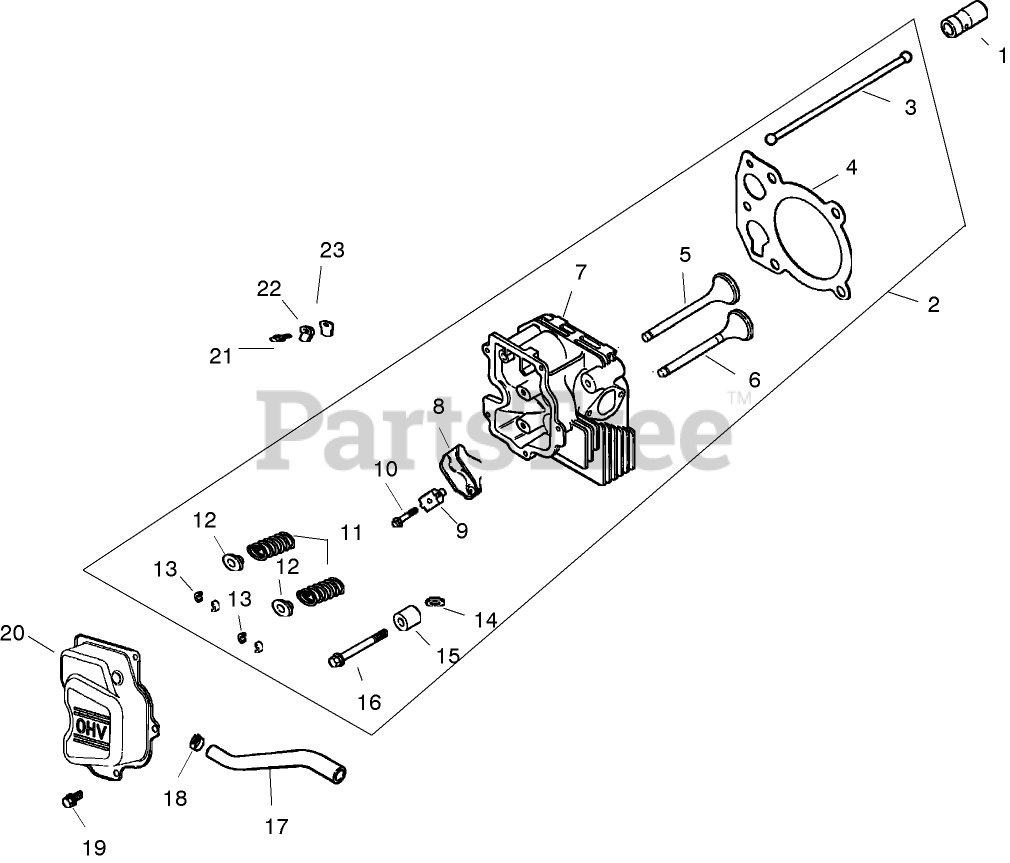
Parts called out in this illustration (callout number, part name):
1	Lifter-Valve
2	Cylinder Head Kit (Includes 3-17, carburetor gasket (2), air cleaner base gasket, exhaust manifold gasket)
3	Rod-Push
4	Gasket-Head, Cylinder
5	Valve-Intake (STD)
6	Valve-Exhaust (STD)
7	Head-Cylinder
8	ARM-ROCKER
9	Pivot-Arm, Rocker
10	SCREW-FLANGE (M6X1.0X34)
11	Spring-Valve
12	CAP-SPRING, VALVE
13	RETAINER KIT
14	Washer-Flat (1/2)
15	Spacer-Head Bolt (Exhaust Port)
16	Screw-Flange, Hex (M10x1.5x37)
17	Hose-Breather
18	CLAMP-HOSE, SPRING (1/2)
19	SCREW-FLANGE, THREAD FORMING (M6X1.0X16)
20	Cover-Valve
21	SCREW-HHFTF (M5X.80X10)
22	Retainer-Reed, Breather
23	REED-BREATHER
